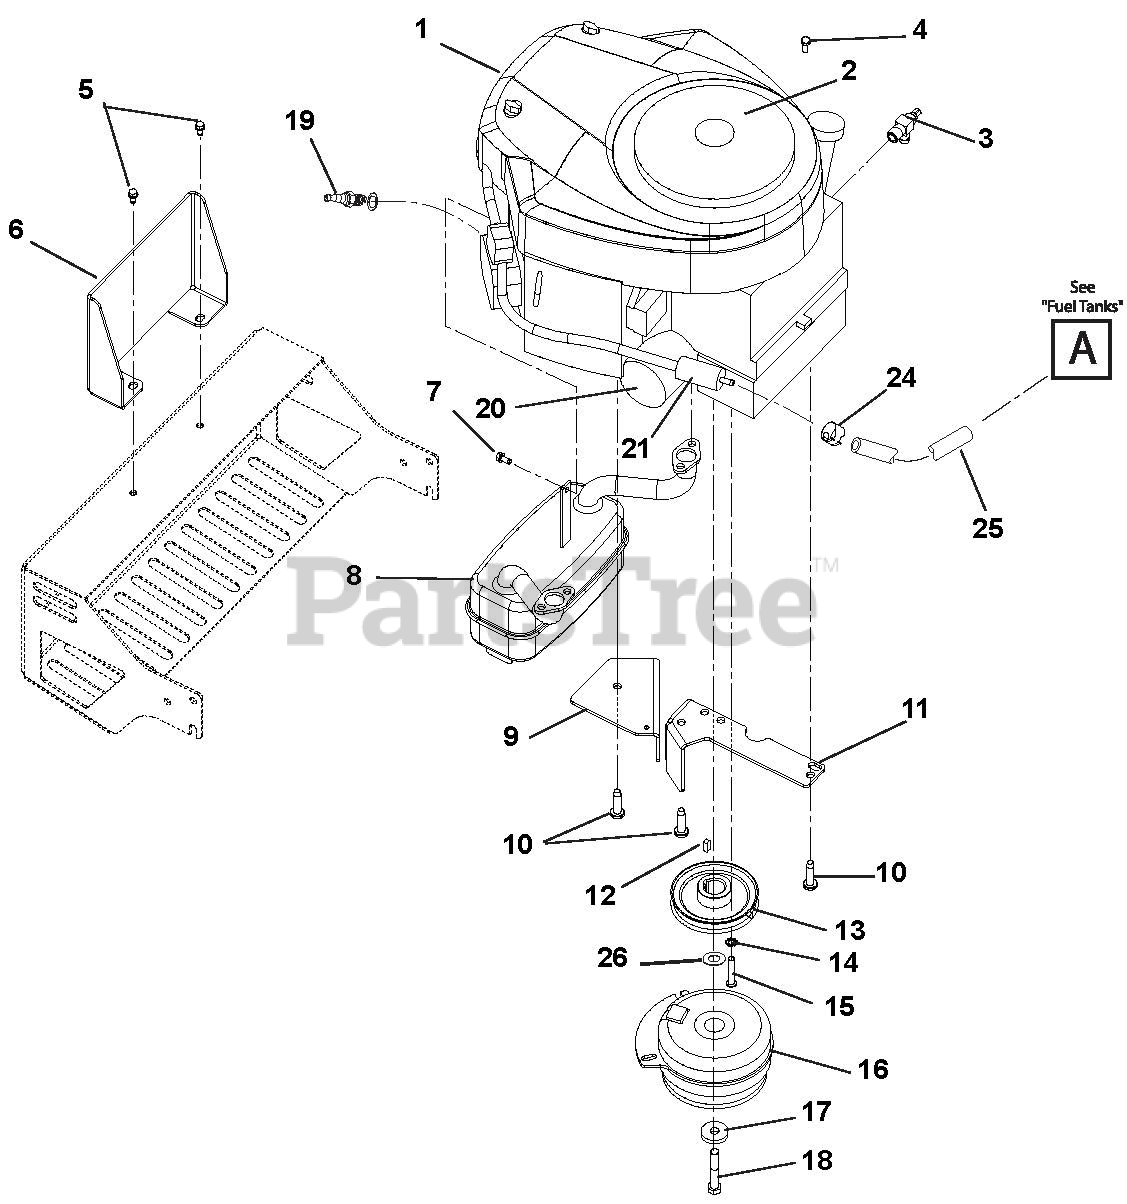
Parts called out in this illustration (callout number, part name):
1	Engine, Briggs & Stratton 26HP ELS
1	Engine, 24HP Briggs & Stratton ELS
1	Engine, 26HP Briggs & Stratton ELS
2	Guard, Briggs and Stratton Engine
3	Drain, .50 Oil
4	Screw, 8-16 x .87 PHPAN 3 LOBE
5	Screw, Tapping .38-16 x .75 Hex Washer Head Thread
6	Briggs and Stratton Carburetor Guard, Black
7	Screw, Tapping .25-20 x .50 Hex Washer Head Thread
8	Muffler Assembly
9	Guard, Clutch Wire- CZ
10	Bolt, Tapping .38-16 x 1.5
11	Weldment, Clutch Stop
12	Key, Square .25 x .625 x .25
13	Sheave, 4.831 x 1.002 Engine
13	Sheave, 4.831 x 1.127
14	Washer, Locking-EXT .326 x .599 x .031
15	Bolt, Button Head .31-18 x 1.75
16	Clutch, Electric
17	Washer, Flat-Steel .463 x 1.375 x .25
18	Bolt, Hex .44-20 x 2.50 Grade 5
19	Plug, Spark
20	Filter, Oil Briggs and Stratton
21	Filter, Fuel Briggs and Stratton
21	Filter, Air Briggs and Stratton
21	Filter, Air Pre- Briggs and Stratton
24	Clamp, Fuel Line
25	Hose, .25 Low-PERM Bulk Gas
26	Washer, Thrust 1.125 x 1.750 x .123
